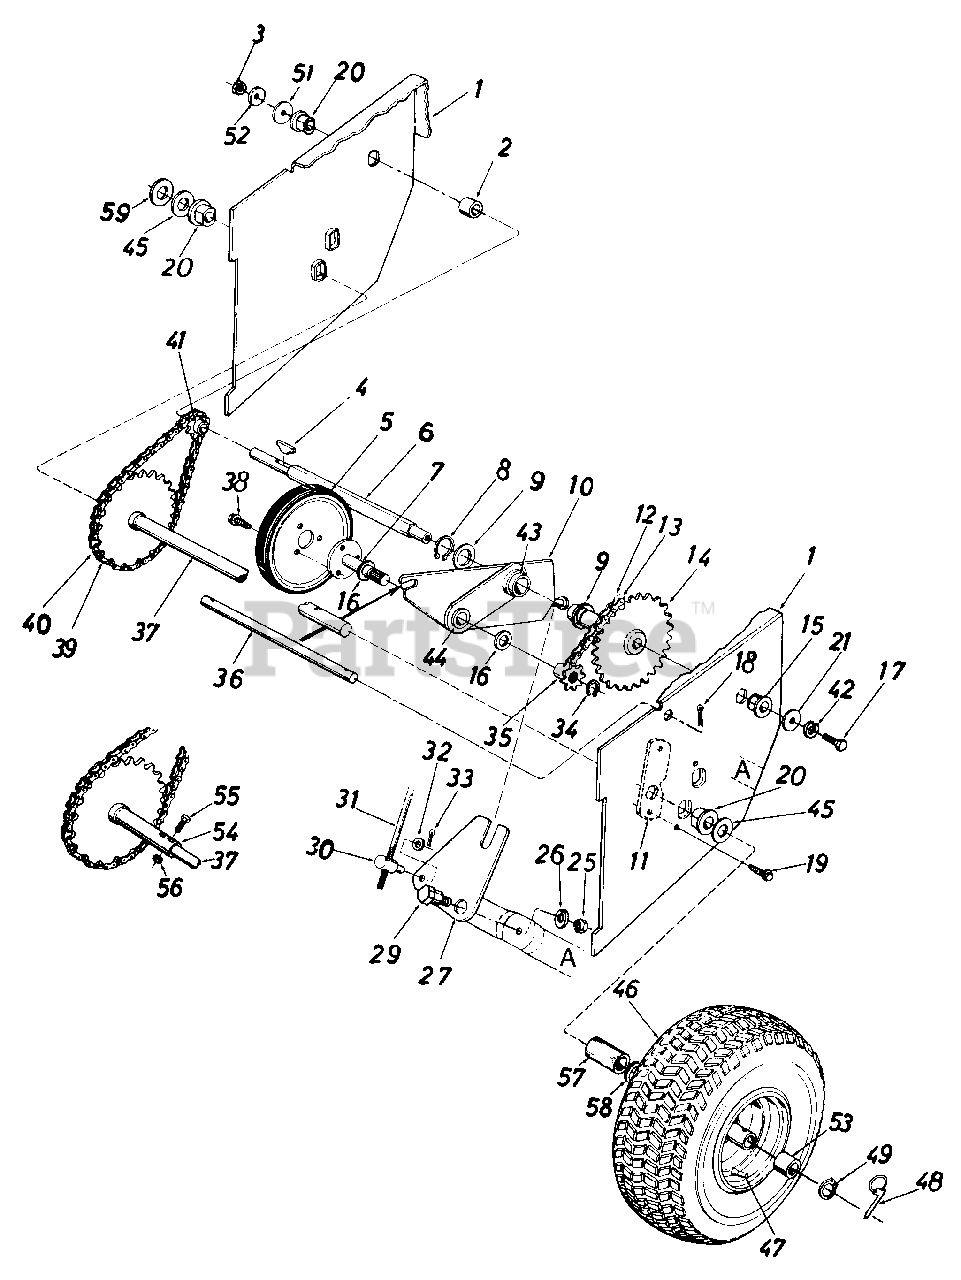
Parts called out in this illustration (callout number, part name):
1	Frame Ass'y.
2	Spacer .50" I.D. x .75" O.D. x.78" Lg.
3	Hex Ins. L-Nut l/2-20 Thd.
4	#4 Hi-Pro Key 3/32 x 518" Dia.
5	Friction Wheel Ass'y.
6	Hex Shaft
7	Friction Wheel Mounting Plate Ass'y.
8	Snap Ring 1.00" Dia. Shaft
9	Fl-Wash. 1.00" x 1.63" O.D. x .03
10	Sliding Bracket Ass'y.
11	Axle Plate 1.75" x 3/16"
12	#41 Chain l/2" Pitch x 35 Links
13	Master Link for #41 Chain
14	32 Teeth Sprocket Ass'y.
15	Hex Flange Brg. 630" I.D.
16	Fl-Wash. .62" I.D. x 1.00" O.D. x .06
17	Hex Lock Bolt 5/16-18 x .62" Lg.
18	Cotter Pin 3/32" Dia. x 75" Lg.
19	Hex Self-Tap Scr. 5/16-24 x 5" Lg
20	Hex Flange Brg. .751" I.D.
21	Fl-Wash. .34" I.D. x 1.12" O.D. x .125
25	Hex Jam Nut 3/8-16 Thd.
26	L-Wash. 3/8" I.D.
27	Shifting Linkage Bracket
29	Shld. Bolt .625" Dia. x 170" Lg.
30	Adjustment Ferrule
31	Shifting Rod 5/16" Dia. x 32.50" Lg.
32	Fl-Wash. .34" I.D. x .64" O.D. x .06
33	Cotter Pin 8/32" Dia. x .75" Lg.
34	Snap Ring .562" Dia. Shaft
35	Sprocket 7 Teeth x 50" Pitch
36	Shaft 50" Dia. x 9 50" Lg.
37	32 Teeth Wheel Axle Ass'y.
38	Hex Wash. Hd. Self-Tap Scr. 5/16-24 X .50" Lg.
39	#420 Chain 1/2" Pitch x 35 Links
40	Master Link for #420 Chain
41	8 Teeth Center Sprocket
42	L-Wash. 5/16" I.D.
43	Bearing
44	Bronze Bearing
45	Fl-Wash. .76" I.D. x 1.49 O.D.
46	Wheel Assembly
47	Air Valve
48	Klick Pin
49	Snap Ring .75 Dia.
51	Fl-Wash. .53 I.D. x 1.25 O.D. x .10
52	Bell-Wash. .50 I.D. x 1.0 O.D. X .075
53	Sleeve Brg.
54	30 Teeth Sprocket Hub Ass'y.
55	Hex Bolt 1/4-28 X 1.5"
56	Hex L-Nut 1/4-28 Thd.
57	Spacer .75" I.D.
58	Fl-Wash. .793" I.D.
59	Fl-Wash. 76" I.D. x 1.49" O.D.
